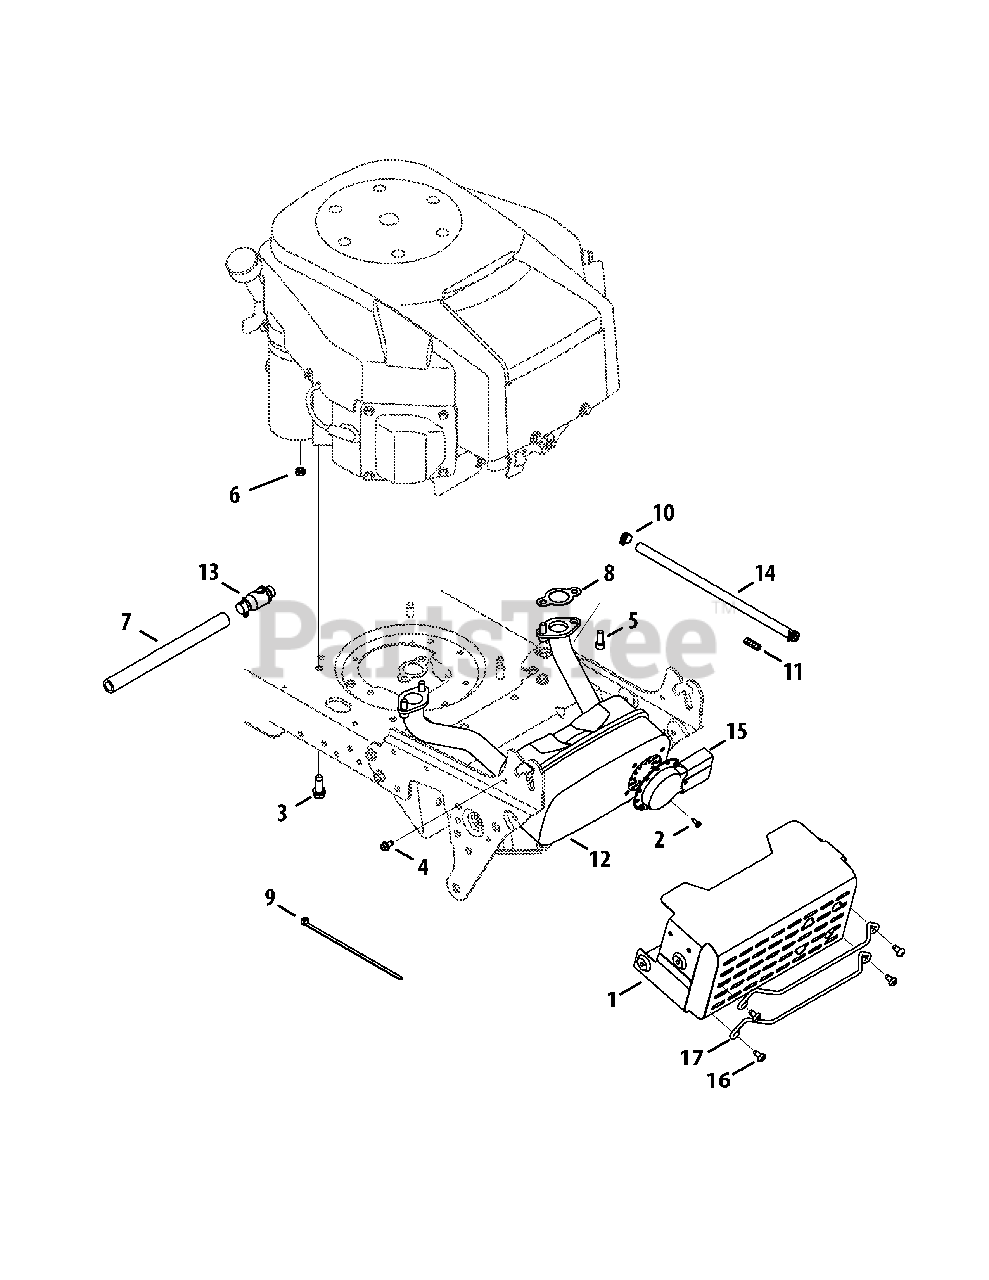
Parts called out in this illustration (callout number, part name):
1	Shield Ass’y, Muffler
2	Screw, Ab, #8-18, 0.500,
3	Screw, Self-tapping, 3/8-16, 1.000,
4	Screw, Self-tapping, 1/4-20, 0.500,
5	Screw, Socket Head, 5/16-18, .750
6	Nut, Sems, 1/4-20
7	Hose, Extension, Oil Drain
8	Gasket, Exhaust,Kohler
9	Cable, Tie, 3/16 x .05 x 7.4
10	Clamp, Hose, .490 Dia.
11	Vent Hose
12	Muffler, Kohler Twin
13	Drain, Oil
14	Hose, Fuel, Low Permeation, 1/4
15	Muffler Deflector Long
16	Pan Torx Screw 1/4
17	Muffler Guard Rod
